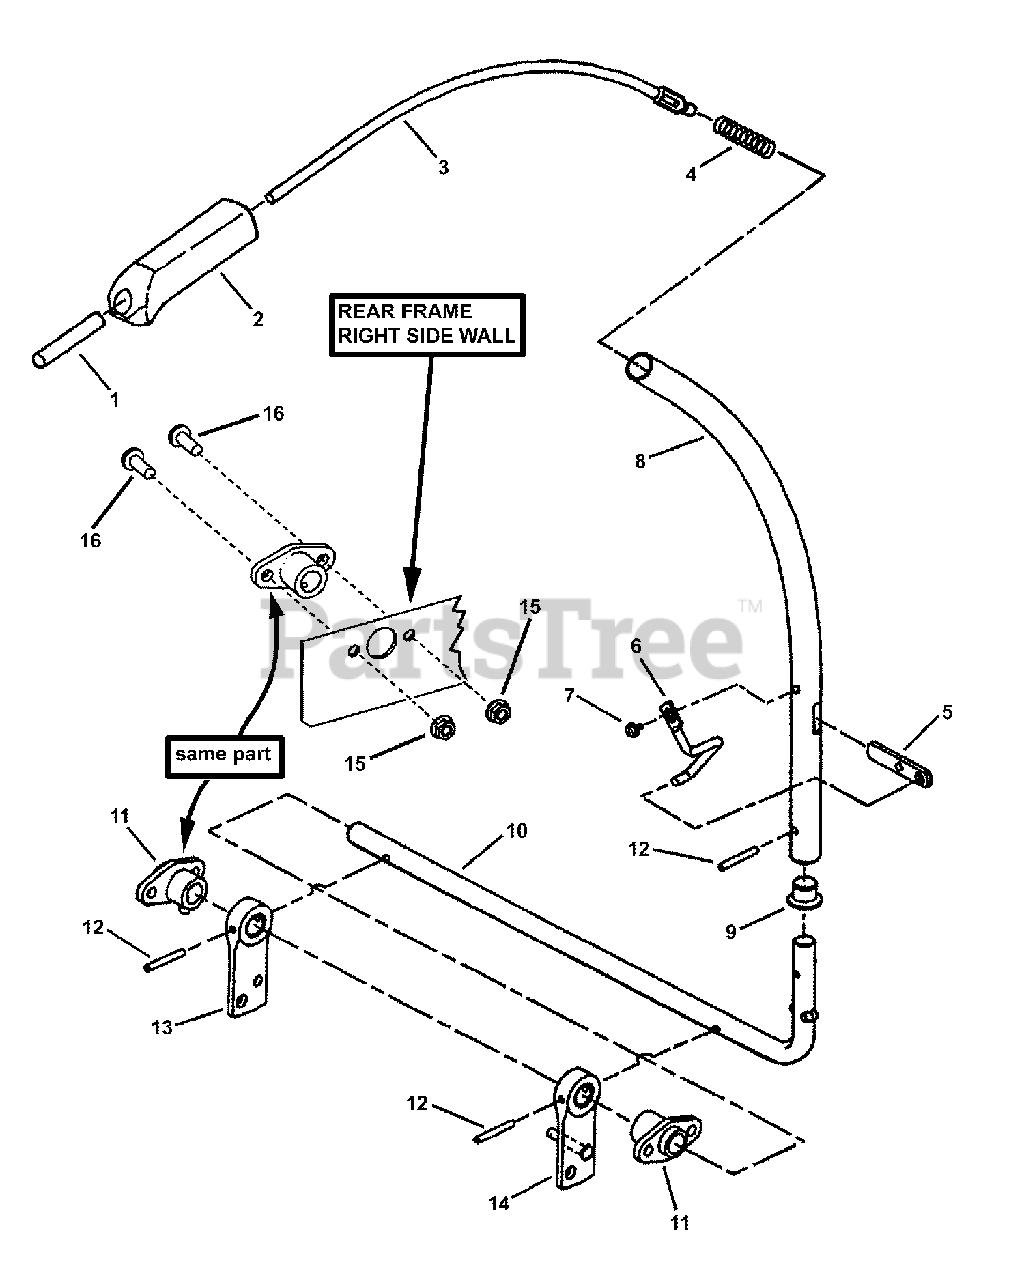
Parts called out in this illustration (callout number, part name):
1	GRIP, 5/16 x 2-1/2" Vinyl
2	GRIP, Brake/Clutch Handle
3	ROD, Park Brake
4	SPRING, Clutch/Brake Release
5	ARM, Brake/Clutch Lever
6	PIVOT, Brake/Clutch Lever
7	SCREW, 1/4-20 x 3/8" Hex Washer Self-Tap
8	TUBE, Clutch/Brake Lever
9	BUSHING, Nylon
10	ROD, Clutch/Brake
11	ASSEMBLY, Foot Shaft Pivot
12	PIN, 3/16 x 1-1/2" Roll
13	ARM, Brake/Clutch
14	WELDMENT, Brake/Clutch Arm
15	NUT, 5/16-18 Hex Flange Lock, GR5
16	SCREW, 5/16-18 x 7/8" Pan Head Self-Tap (Torx)
